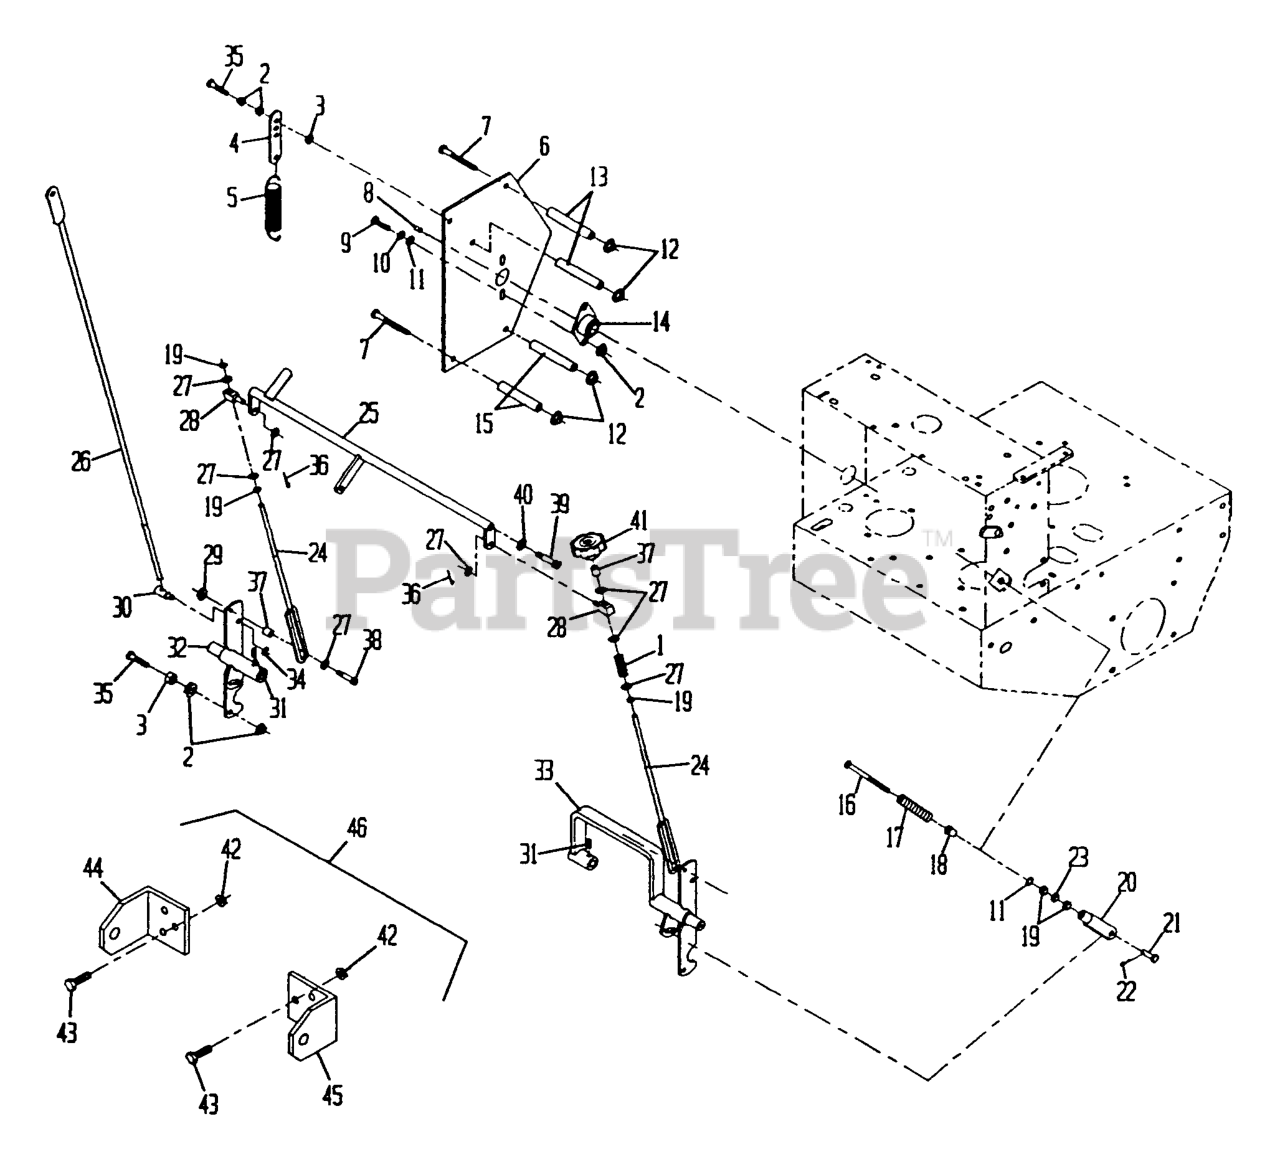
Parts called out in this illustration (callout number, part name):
1	SPRING-COMPRESSION
4	TAB-SPRING, EXTENSION
5	SPRING-EXTENSION
10	WASHER-LOCK
13	SPACER-SHIELD
14	BEARING-FLANGE, SIDE
15	SPACER-SHIELD
16	BOLT-RETURN, NEUTRAL
17	SPRING-RETURN, NEUTRAL
18	BUSHING-FLANGED
20	YOKE-ADJUSTABLE
21	PIN-CLEVIS
22	PIN-COTTER
25	CRANK-CONTROL, SPEED
26	ROD-LEVER, DRIVE
31	SCREW-SET
38	SCREW-HSH
39	SCREW-HSH
41	KNOB-TRACKING
45	BRACKET,SULKY RH
46	Sulky Kit
